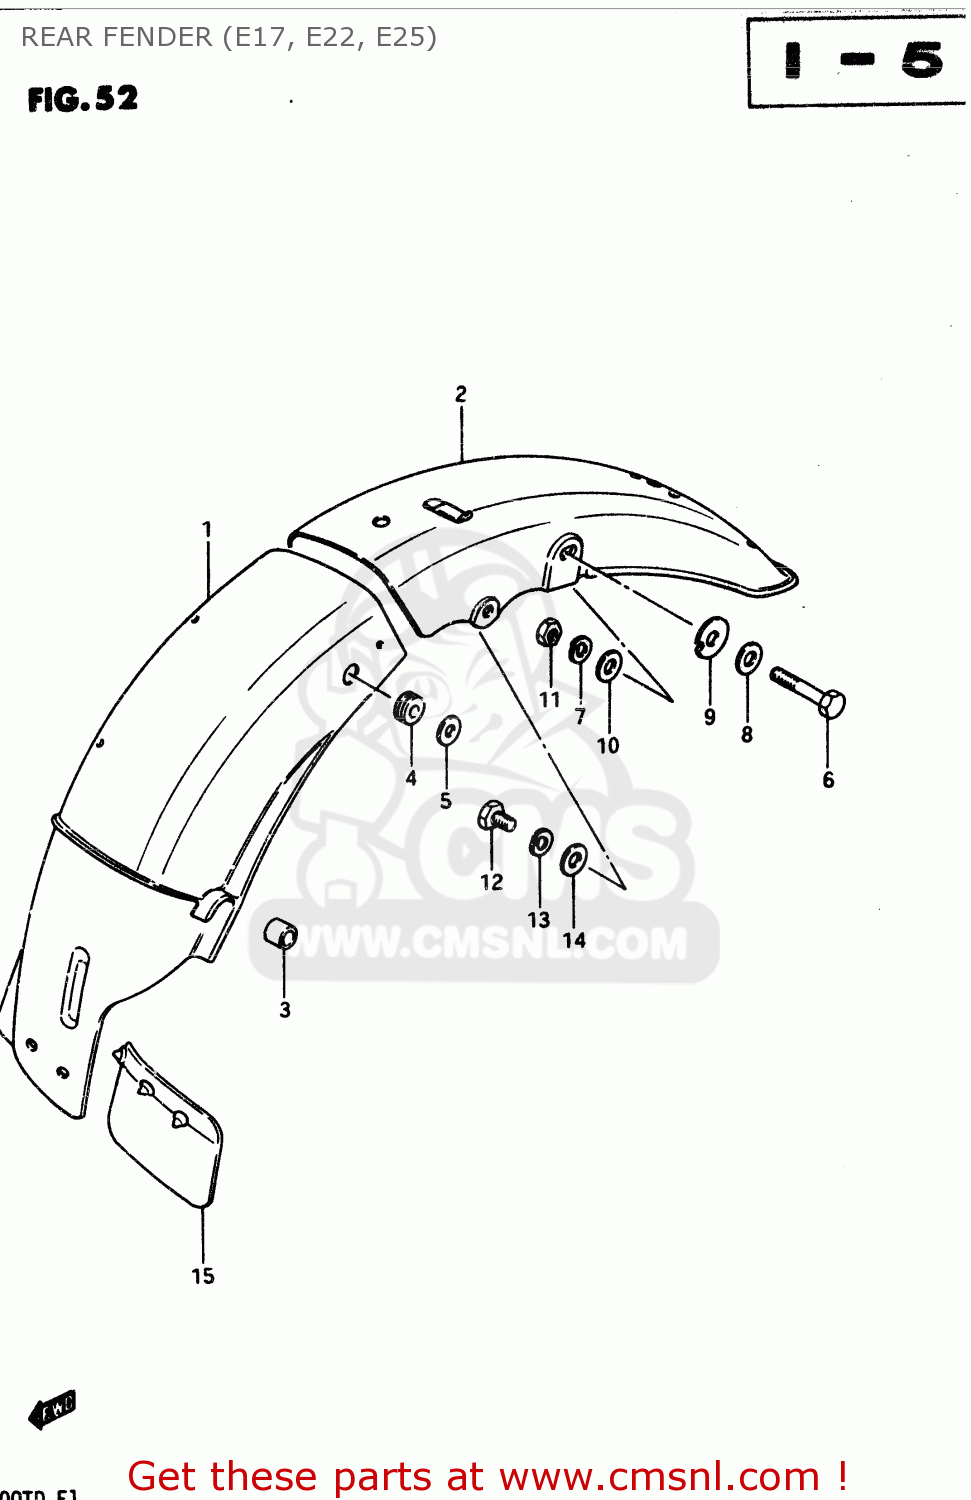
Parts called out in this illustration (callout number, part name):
1	BODY, REAR FENDER FRONT
2	BODY, REAR FENDER REAR
3	CUSHION
4	CUSHION
5	WASHER
6	BOLT
7	LOCK WASHER
8	WASHER
9	WASHER (8.5X30X5)
10	WASHER
11	NUT
12	BOLT
13	LOCK WASHER
14	WASHER
15	GUIDE,RR FENDER MUD
